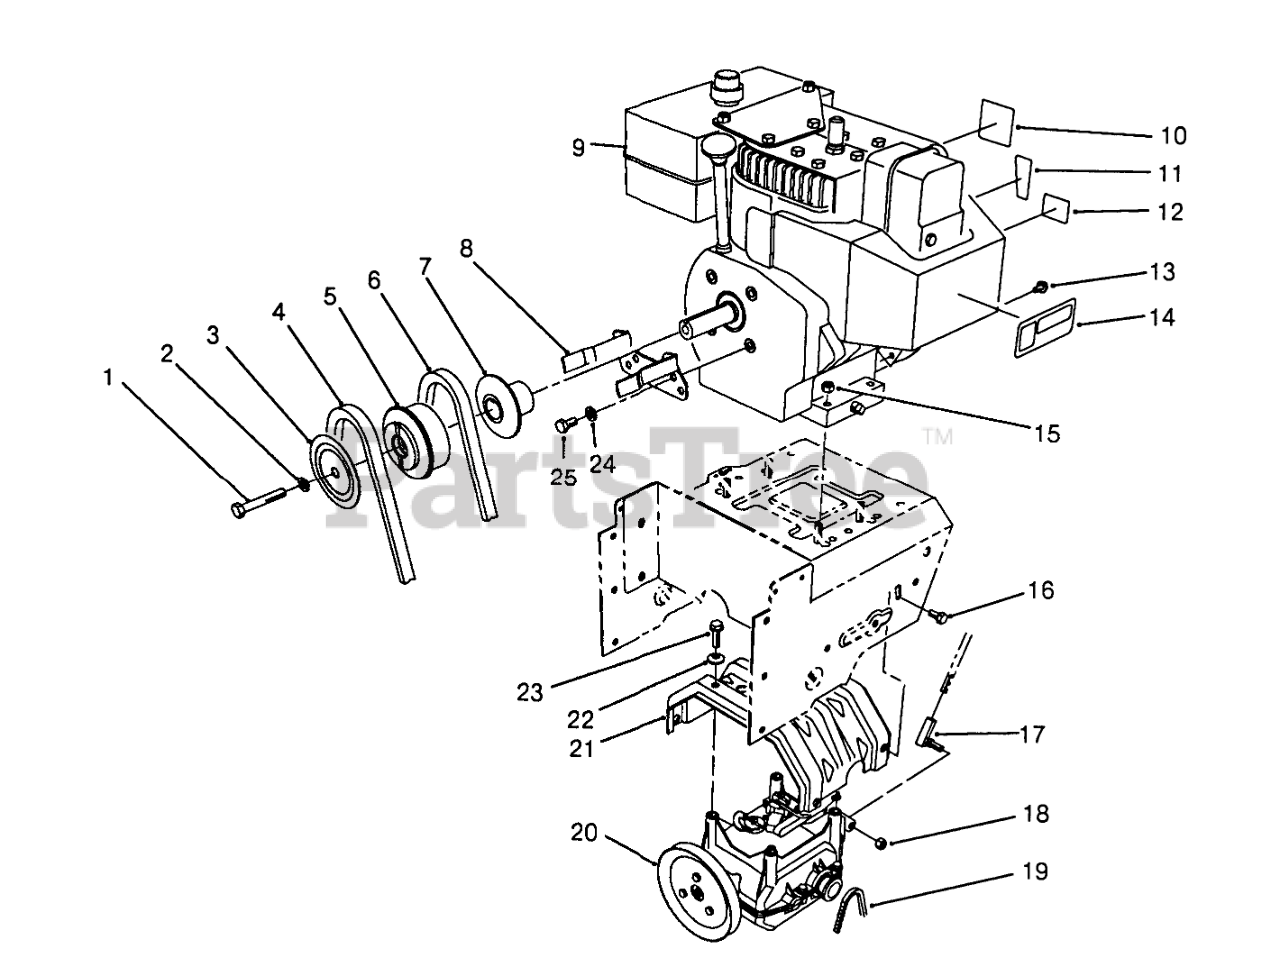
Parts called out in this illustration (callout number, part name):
1	SCREW-HH
2	WASHER-LOCK
3	SHEAVE-HALF, IMPELLER
4	V-BELT
5	PULLEY-ENGINE, CENTER
6	V-BELT-TRACTION
7	SHEAVE-HALF, TRACTION
8	Guide-Belt
10	DECAL-PRIMER
11	DECAL-THROTTLE
12	DECAL-CHOKE
13	SCREW-HWH
14	DECAL-HOT SURFACE, WARNING
15	NUT-HF
16	SCREW-HHF
17	JOINT-BALL
18	NUT-LOCK
19	CHAIN
20	Transmission Assembly
21	Frame-Transmission
22	WASHER-SPRING
23	SCREW-HWHTF
24	WASHER-LOCK
25	SCREW-HH
